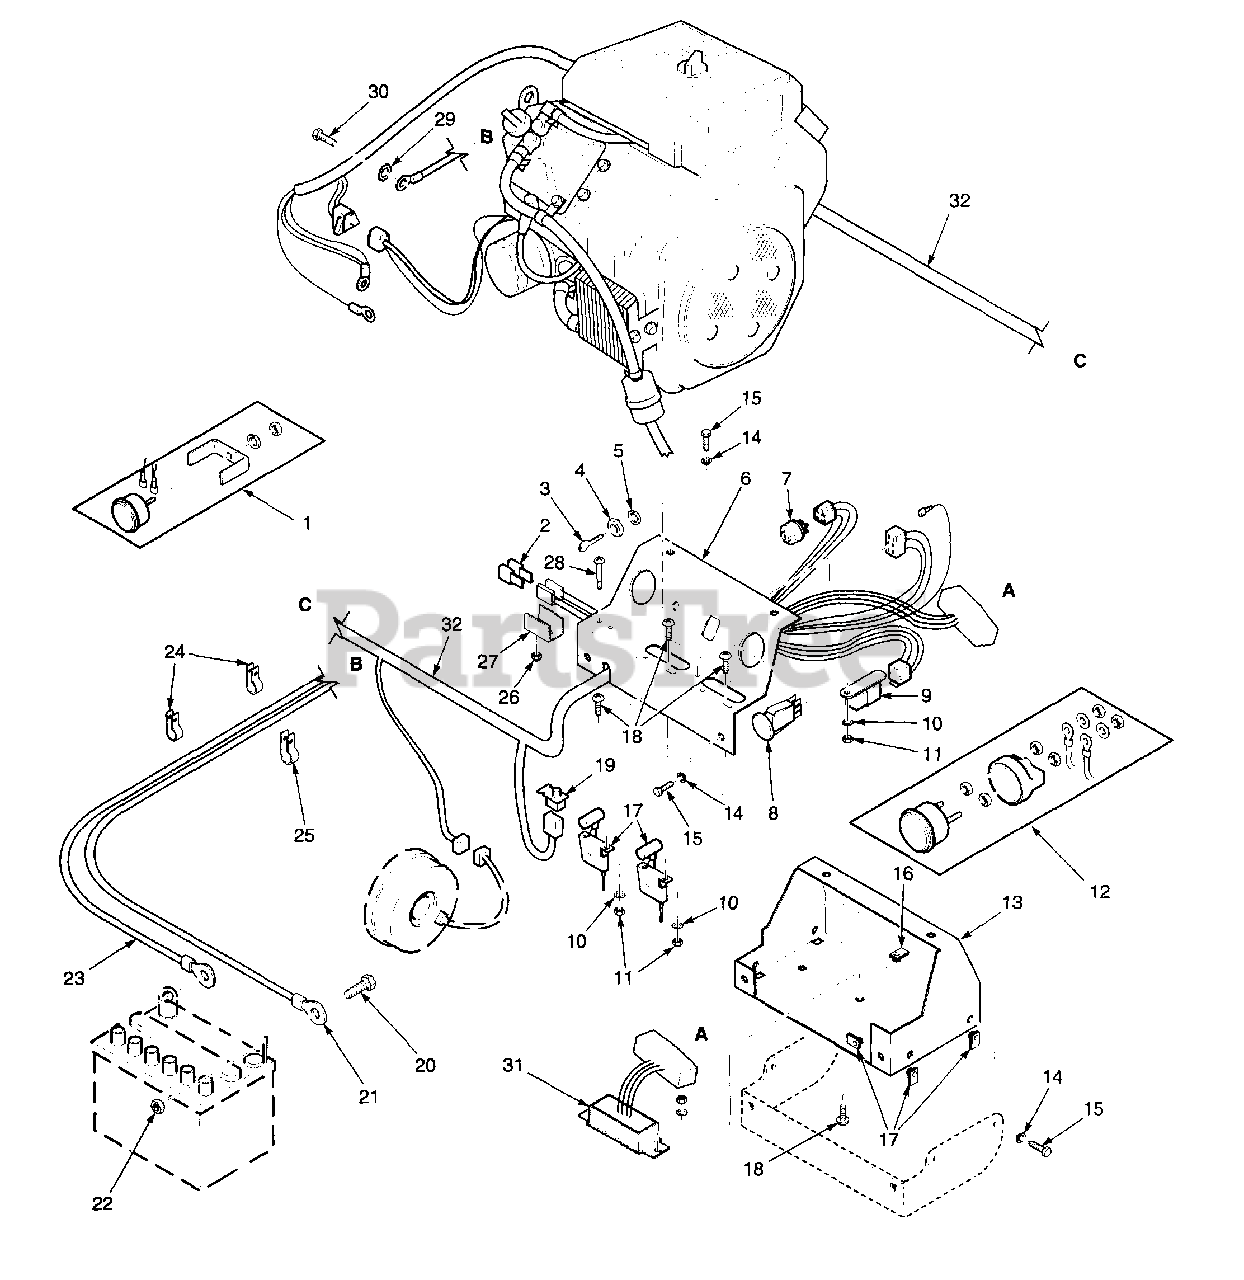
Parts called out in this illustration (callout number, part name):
1	Hour Meter
2	Fuse, 20 AMP
3	Key & Ring Assembly
4	Nut, Hex 5/8-32
5	Lockwasher, 5/8" Internal
6	Instrument Panel, Top
7	Key Switch
8	Switch, PTO
9	Relay
10	Lockwasher, #10 External Tooth
11	Nut, Hex #10-32
12	Ammeter
13	Base, Instrument Panel
14	Lockwasher, 1/4"
15	Bolt, Hex Head 1/4-20 x 3/4"
16	U-Nut, 1/4-20
17	Throttle And Choke Controls
18	Screw, Phillips Washer Head #10-32 x 1/2"
19	Switch, Interlock-Seat
20	Bolt, Hex Head 1/4-20 x 1/2"
21	Cable, Battery - Red 20"
22	Nut, Hex 1/4-20
23	Cable, Battery - Black
24	Clamp, Cable 1/2" ID.
25	Clamp, Cable 3/4" ID.
26	Nut, Hex Elastic Stop #10-32
27	Bracket, Fuse Holder
28	Screw, Phillips Washer Head #10-32 x 1-1/2"
29	Lockwasher, 5/16" External Tooth
30	Bolt, Hex Head M8-1.25 x 20
31	Electronic Module
32	Wire Harness, STT
